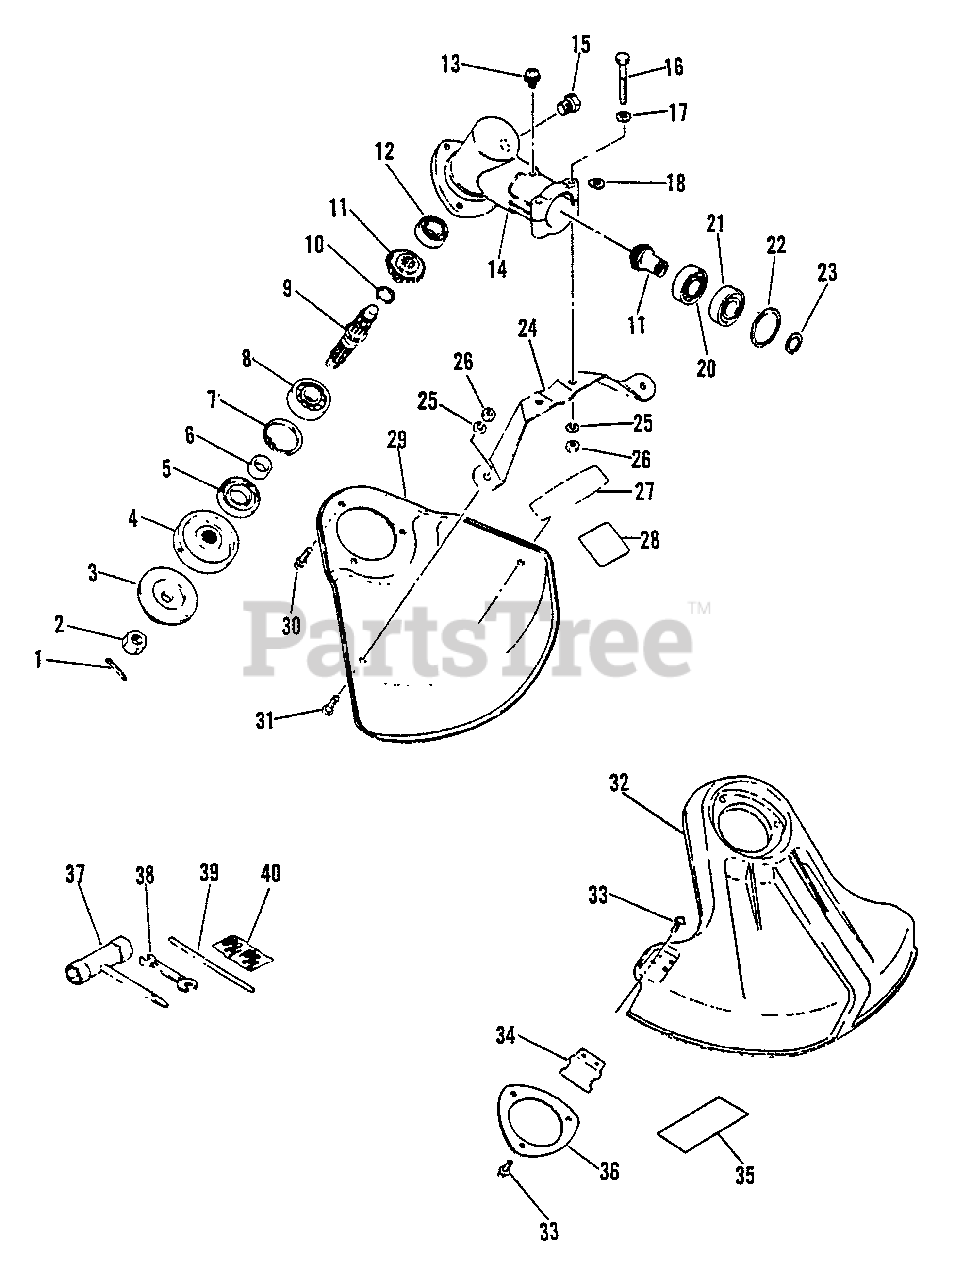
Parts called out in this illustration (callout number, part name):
1	PIN, SPLIT - 2X22
2	NUT - 10 -- LEFT HAND
3	ADAPTOR, BLADE - LOWER
4	ADAPTOR, BLADE - UPPER
5	SEAL, OIL
7	RING, RETAINING - 32
8	BEARING, BALL - 6201
9	GEAR - SHAFT
10	RING, RETAINING - 12
11	GEAR SET - BEVEL
12	BEARING, BALL - 6000
13	SCREW - 5X10
14	CASE, GEAR
15	BOLT - 8X8
16	BOLT - 5X40
17	WASHER - 5
20	BEARING, BALL - 6001
21	BEARING, BALL - 6001
22	RING, RETAINING - 28
23	RING, RETAINING - 12
24	BRACKET, SHIELD
25	LOCKWASHER - 5
27	LABEL - ECHO
28	LABEL - CAUTION
29	DEBRIS SHIELD KIT
30	SCREW - 5X10
31	SCREW - 5X8
32	SHIELD, DEBRIS - PLASTIC
33	SCREW - 5X16
34	KNIFE, TRIMMER LINE
35	LABEL - CAUTION
36	PLATE, SHIELD
37	T-WRENCH - 17X19mm
38	SPANNER - 8X10mm
39	LOCKING TOOL
40	PIN, SPLIT - 2X22
